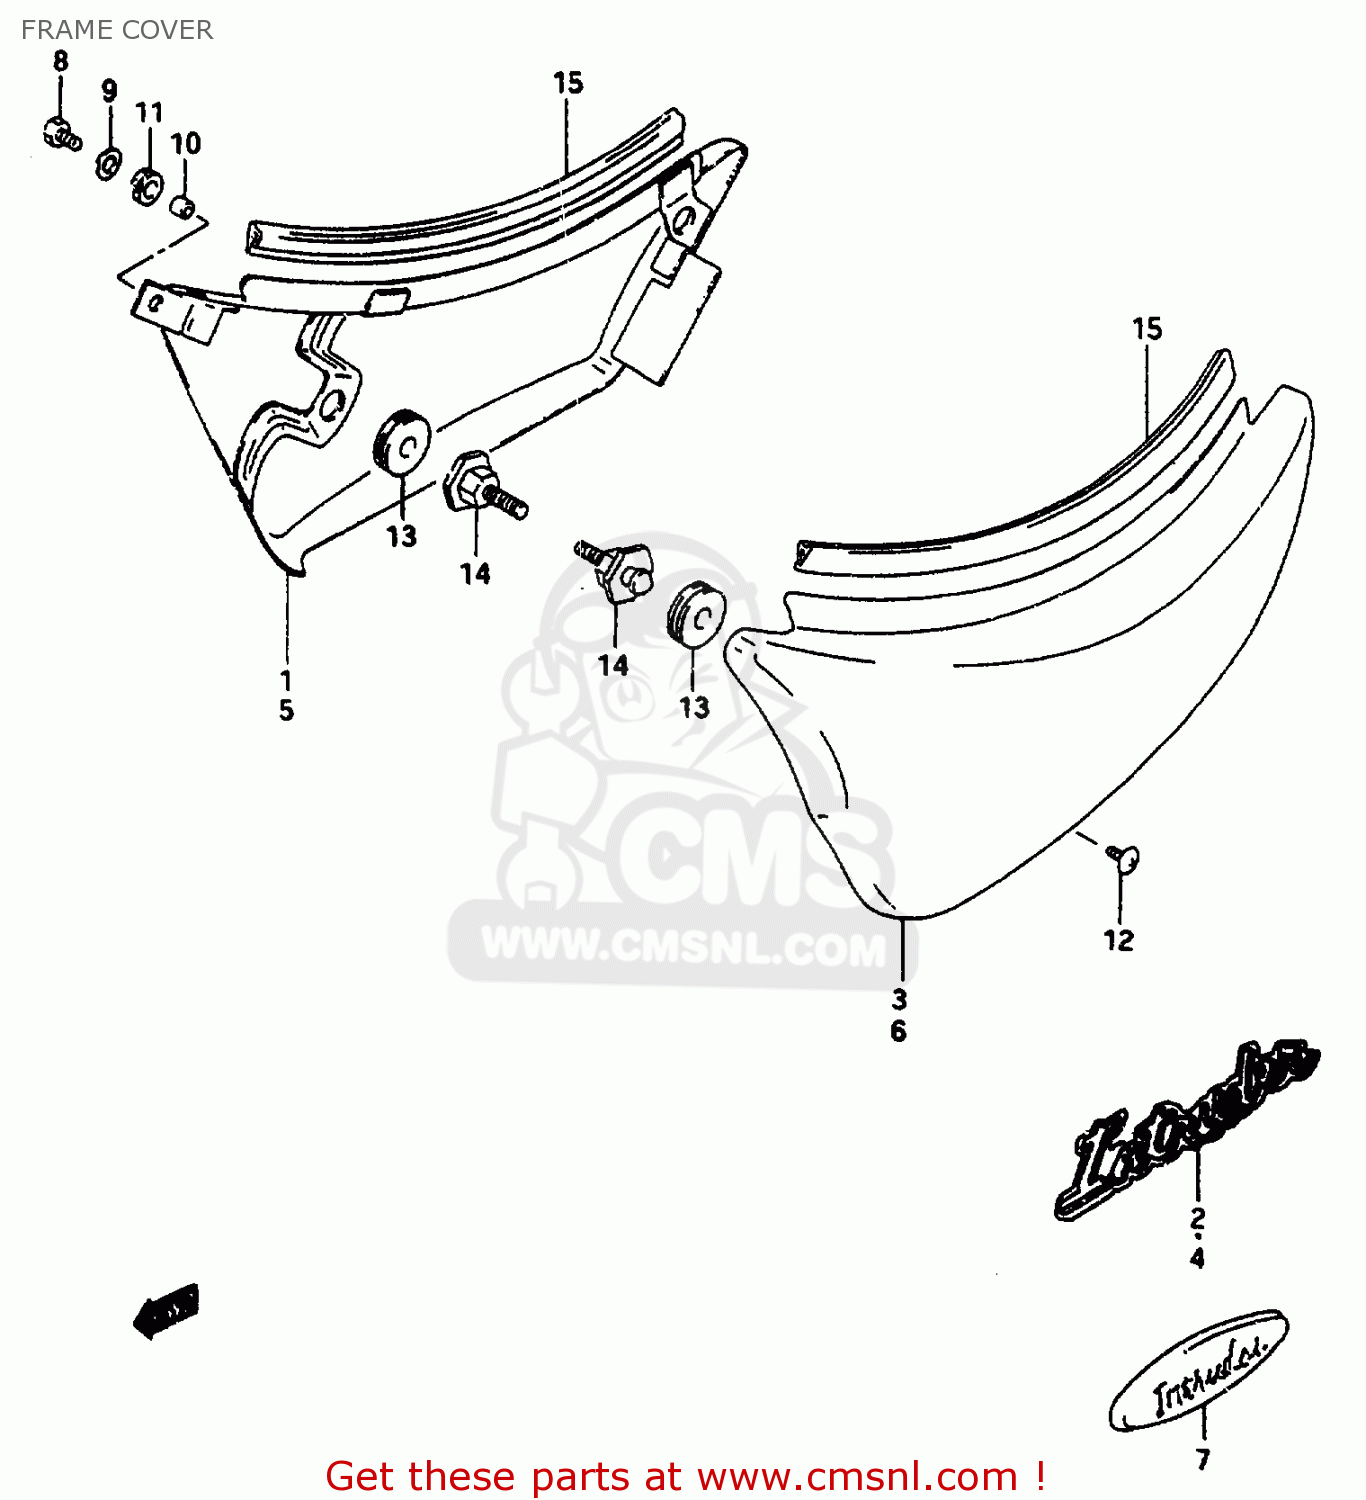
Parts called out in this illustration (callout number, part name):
1	COVER,FRAME,R
2	EMBLEM
3	COVER,FRAME,L
4	EMBLEM
5	COVER,FRAME,R(RED)
6	COVER,FRAME,L(RED)
7	EMBLEM,FRAME COVER
8	BOLT
9	WASHER
10	SPACER (6.1X8X5.2)
11	CUSHION
12	SCREW 6X10
13	CUSHION
14	BOSS,FRAME COVER
15	MOLDING
